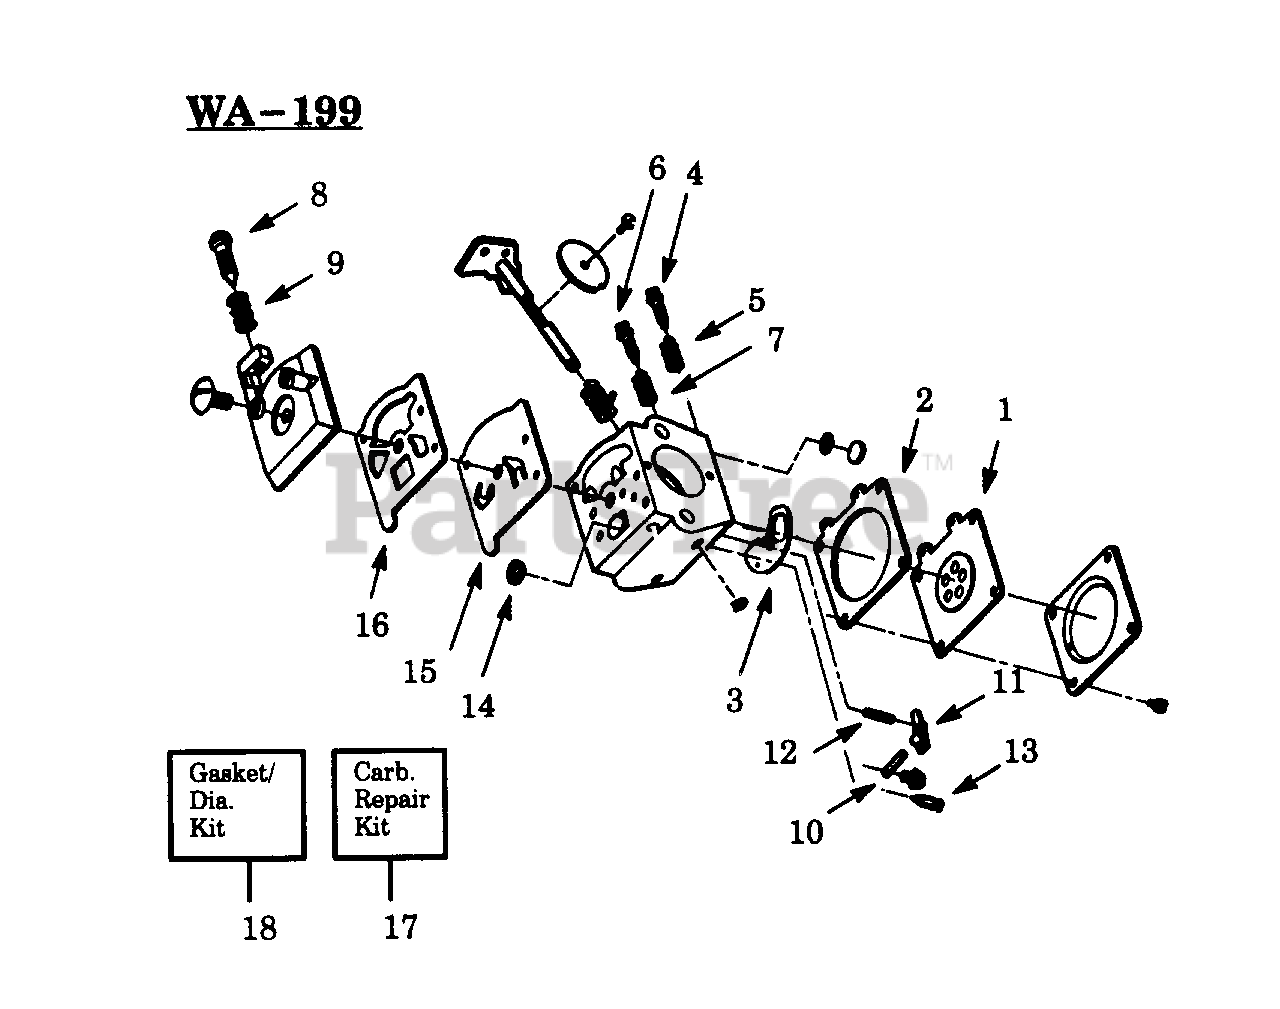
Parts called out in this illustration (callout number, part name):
1	Metering Diaphragm
2	Metering Diaphragm Gasket
3	Circuit Plate Gasket
4	Hi Speed Needle
5	Hi Speed Needle Spring
6	Idle Needle
7	Idle Needle Spring
8	Idle Speed Screw
9	Idle Speed Spring
10	Metering Lever Pin
11	Metering Lever
12	Metering Lever Spring
13	Inlet Needle Valve
14	Inlet Screen
15	Pump Diaphragm
16	Pump Gasket
17	Carb. Kwik Repair Kit (Inc. 1,2,3,12,13,14, 15,16,18)
18	Carb. Gasket/DiaphragmKit (Inc. 1,2,3) Contents)
